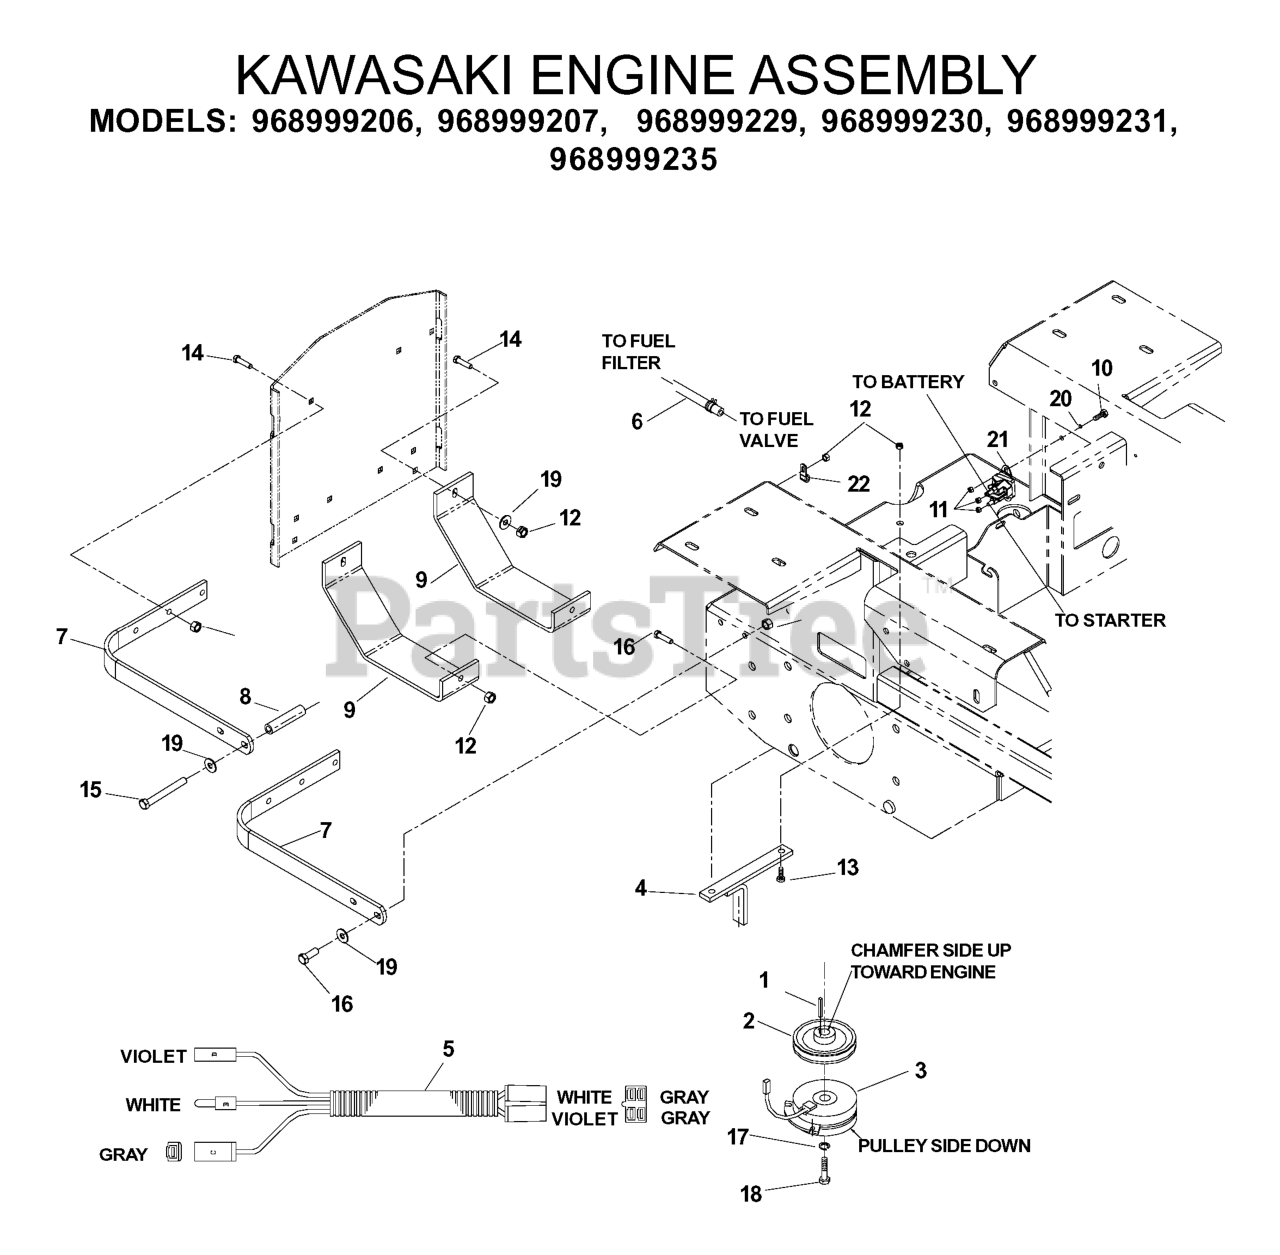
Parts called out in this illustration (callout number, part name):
1	KEY, 1/4 SQ X 1 1/4
3	CLUTCH-200 FT LB(RPLS 5218-102
4	CLUTCH TIE DOWN
5	KAW PIGTAIL
6	FUEL LINE 29.5"
7	ENGINE SHROUD BRKT
9	SKID PLATE
10	HCS 1/4C X 5/8
11	NUT.1/4-20.HEX.NYLOC.ZD
12	NUT 5/16 NYLOC
13	HCS 5/16C X 1 3/4
14	RHSSNB 5/16C X 1.0
15	HCS 5/16C X 4
16	HCS 5/16C X 1
17	WASHER 7/16 LOCK
18	BOLT 7/16F X 2 1/2
19	WASHER 5/16 FLAT
20	WASHER 1/4 INT TOOTH
22	DOUBLE TUBE CLAMP
